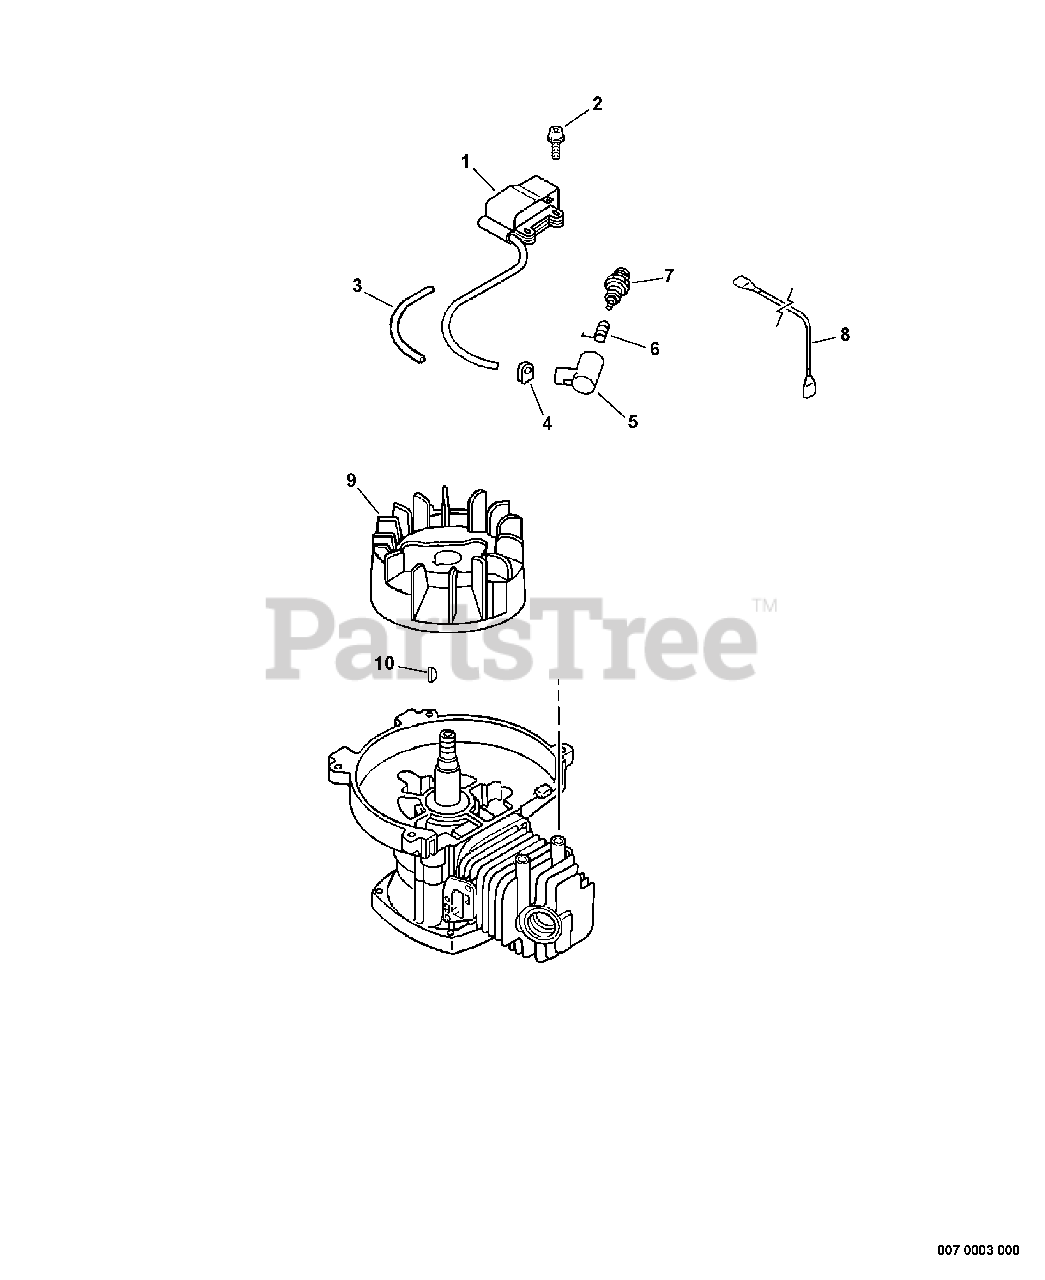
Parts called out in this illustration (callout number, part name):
1	COIL, IGNITION
2	SCREW - 4X20
3	TUBE, INSULATOR
5	CAP, SPARK PLUG
6	TERMINAL, SPARK PLUG CAP
7	SPARK PLUG -- BPMR-7A
8	LEAD - IGNITION
9	FLYWHEEL
